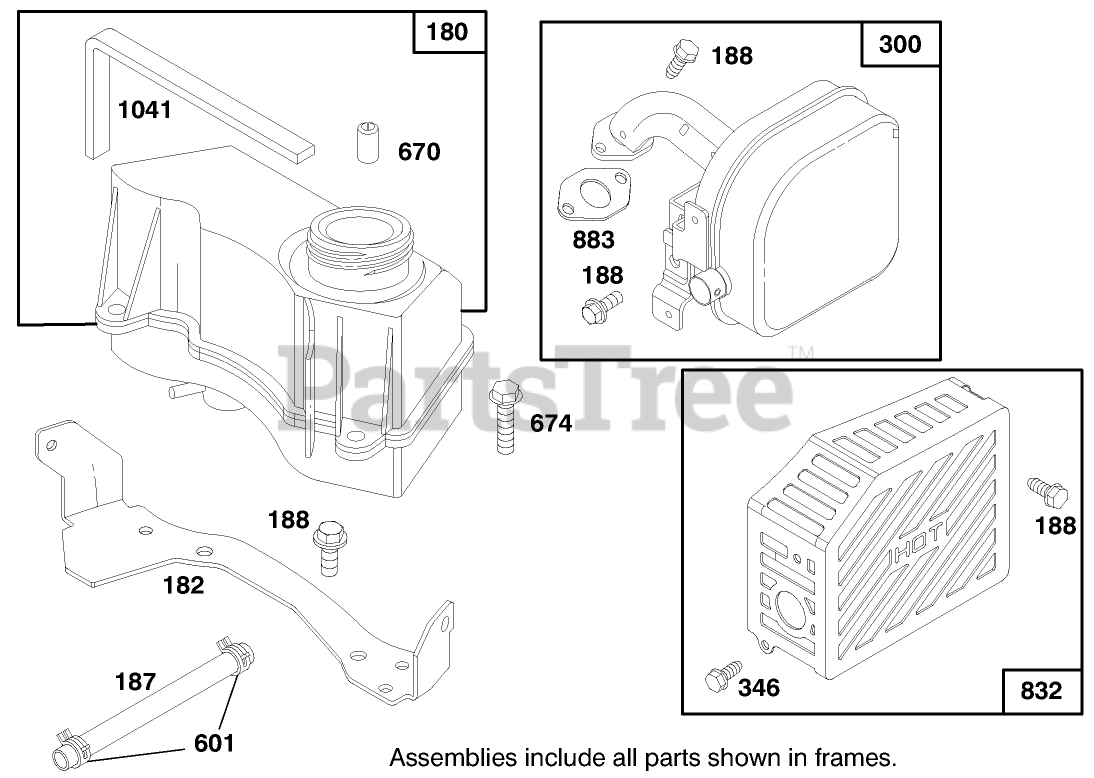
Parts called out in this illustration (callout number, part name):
180	TANK ASSY - FUEL
187	BRACKET - REAR LH
188	SCREW - HEX HEAD
300	MUFFLER - EXHAUST
670	SPACER
674	SCREW - HEX HEAD
